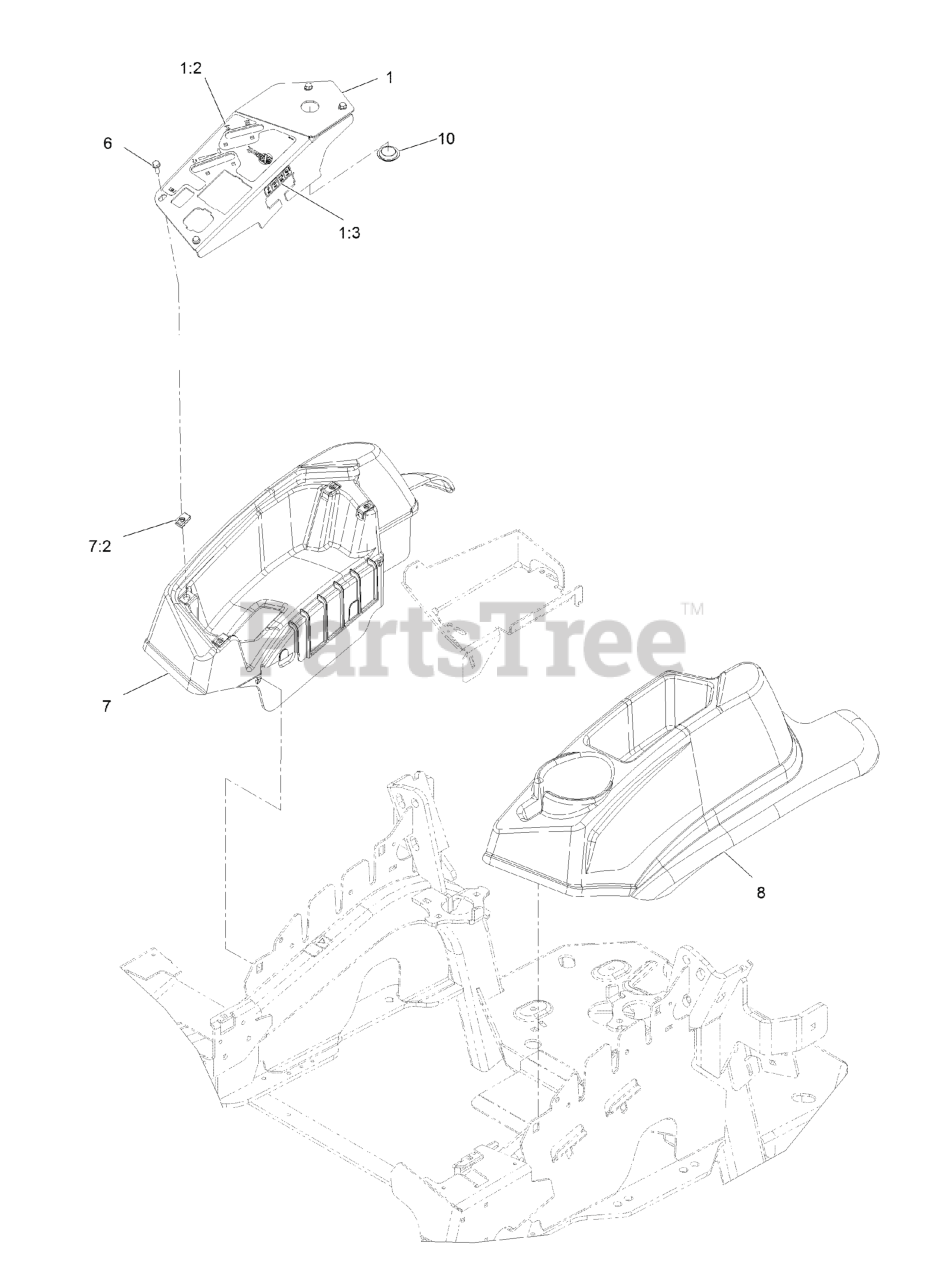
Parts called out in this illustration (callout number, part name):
1	ASM,CONTROL PANEL W/DECAL
1:2	DECAL-CONTROL PANEL EFI
1:3	DECAL-FUSES
5	SCREW-HWH
6	CONSOLE,RH AS ASM
7	CONSOLE, LH AS
8	PLUG-PLASTIC
